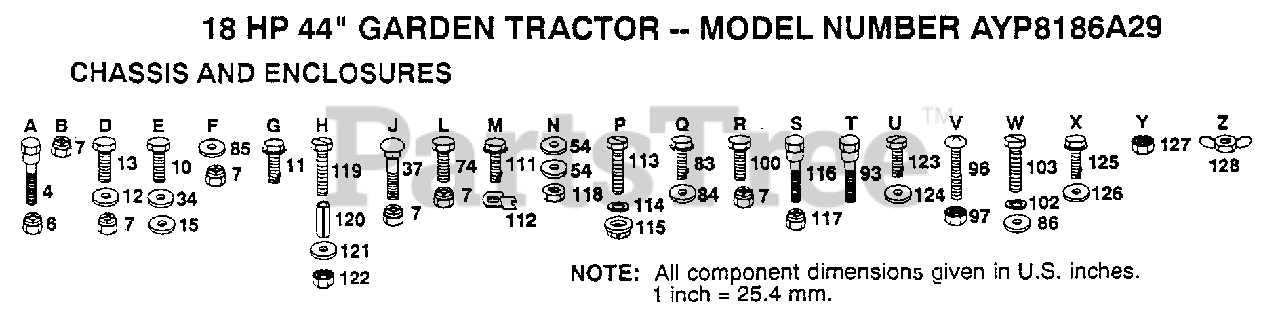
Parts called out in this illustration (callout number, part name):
10	BOLT
11	SCREW
12	WASHER
15	WASHER
34	LOCKWASHER
37	BOLT
54	WASHER PM
83	SCREW TI
84	WASHER HYT
85	WASHER
86	WASHER
93	"BOLT,SHOULDER"
97	"NUT,KEPS"
100	BOLT
102	"WASHER,LOCK"
103	SCREW
112	"""J"" FASTENER LT"
113	SCREW
114	LOCKWASHER
115	WELDNUT
119	SCREW
120	SPACER LT
121	WASHER
123	SCREW
124	WASHER
125	SCREW HEX CRT
126	WASHER
127	NUT
